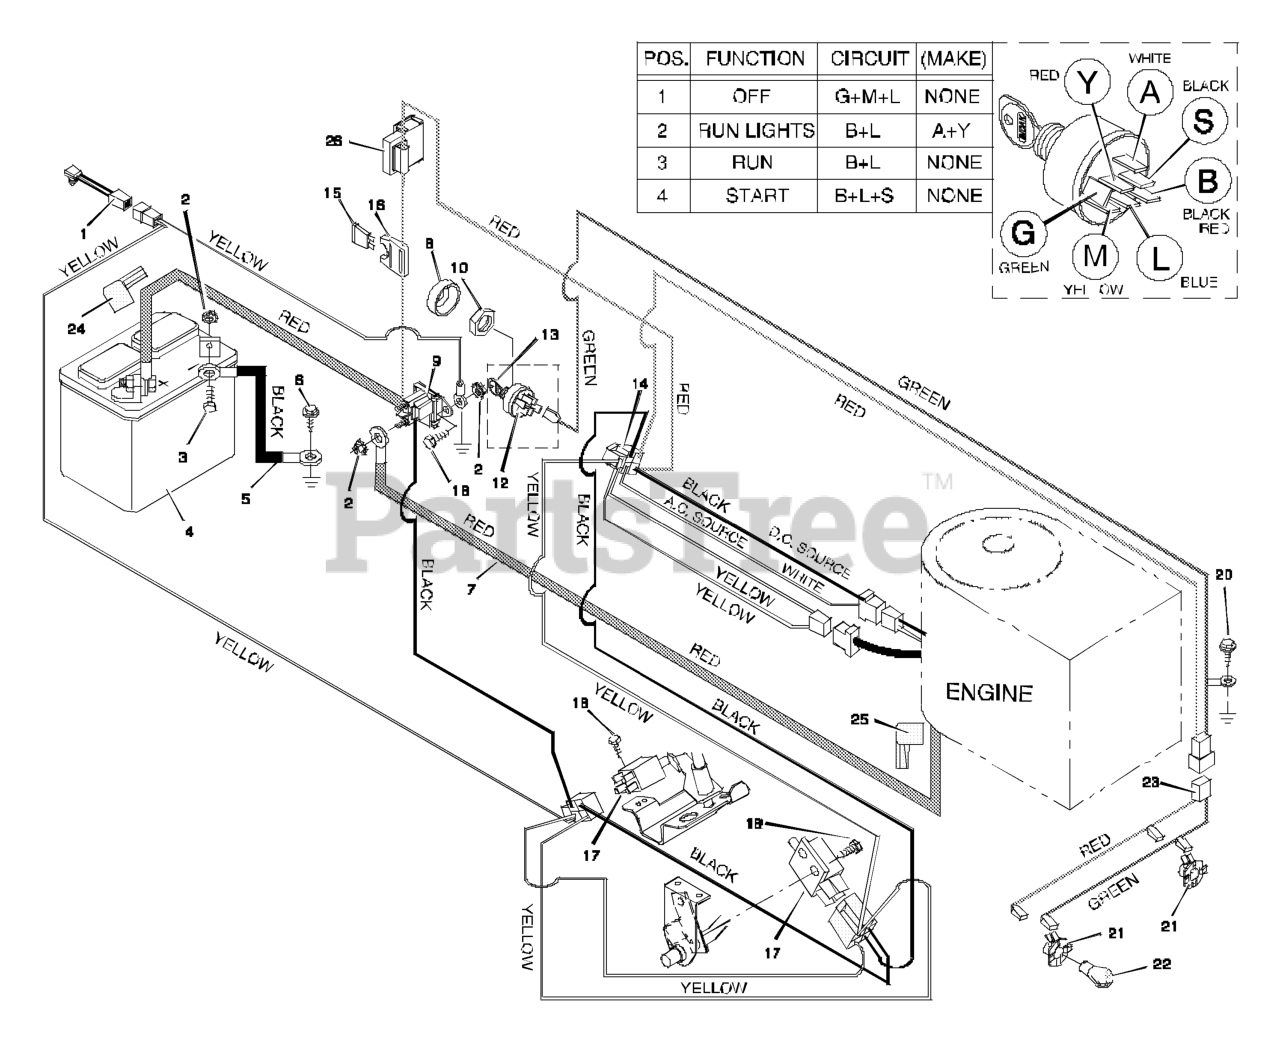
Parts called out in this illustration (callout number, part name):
1	Switch, Seat Sensor
2	Locknut
3	Bolt, Hex
4	Battery
5	Cable, Battery Ground
7	Cable, Red Battery
8	Cap, Ignition
9	Solenoid
10	Nut
12	Switch, Ignition
13	Key, Ignition
14	Harness, Chassis Wire
16	Holder, Fuse
17	Switch, Clutch
20	Screw
21	Socket, Light
22	Bulb, Light
23	Harness, Light Wire
24	Cover, Terminal
25	Cover,
26	Ammeter
